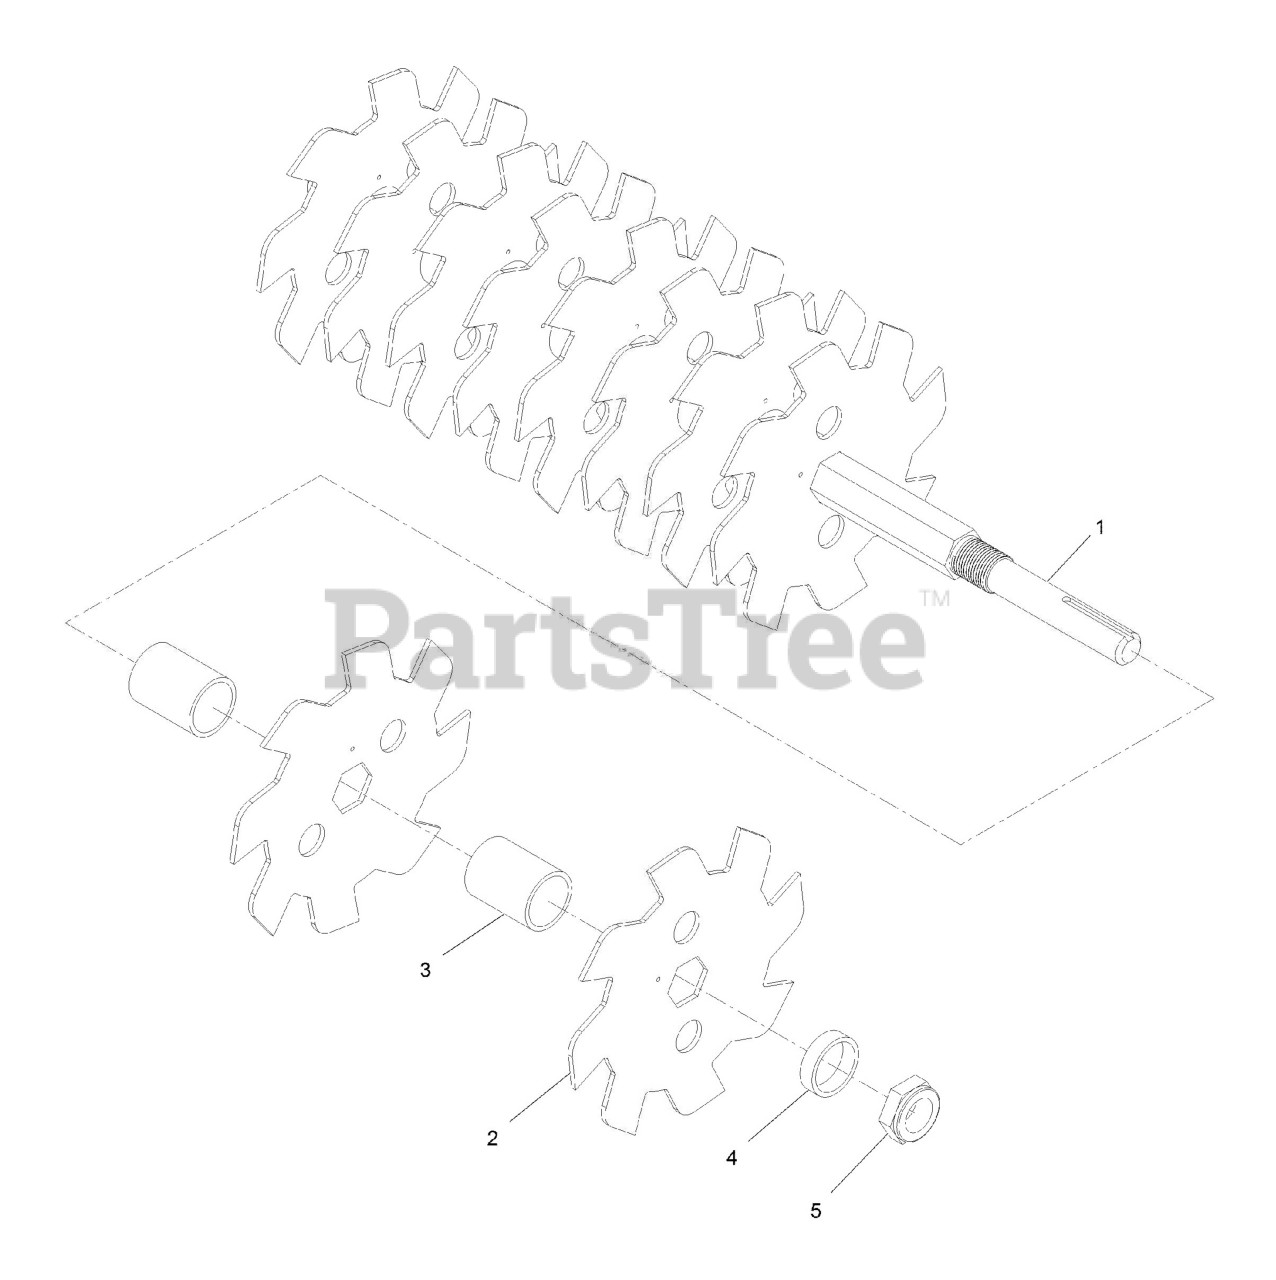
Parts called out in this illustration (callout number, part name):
1	SHAFT-SLICER
2	Blade-Cutting, Seeder
3	SPACER-BLADE
5	NUT-LOCK, NI
